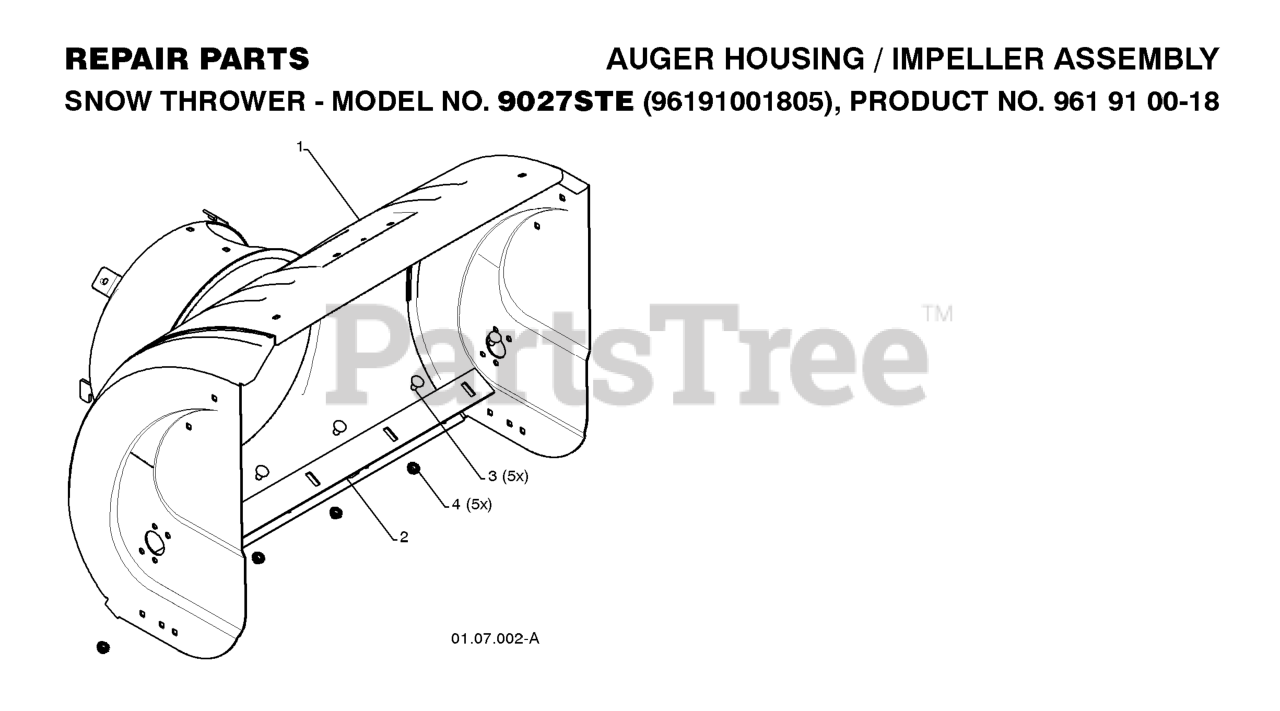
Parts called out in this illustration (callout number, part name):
1	HOUSING, AUGER
2	BAR, SCRAPER
3	BOLT
4	NUT.FLANGE.5/16
